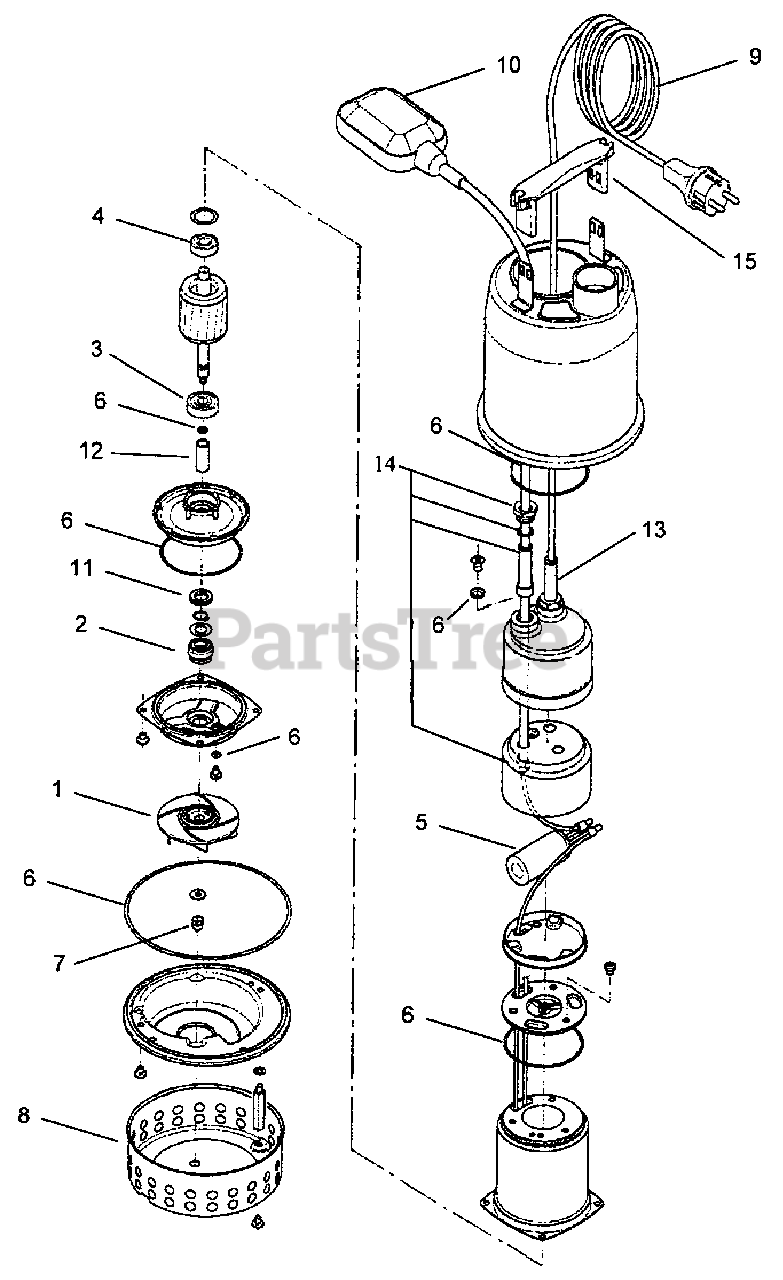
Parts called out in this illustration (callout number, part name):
1	IMPELLER
2	SEAL SET, MECHANICAL
3	BEARING (LOWER)
4	BEARING (UPPER)
5	CAPACITOR (30UF)
6	O-RING KIT
7	NUT, IMPELLER
8	STRAINER
9	POWER WIRE
10	SWITCH, FLOAT
11	LIP SEAL
12	SLEEVE, SHAFT
13	CONNECTOR, POWER WIRE
14	CONNECTOR, FLOAT SWITCH
